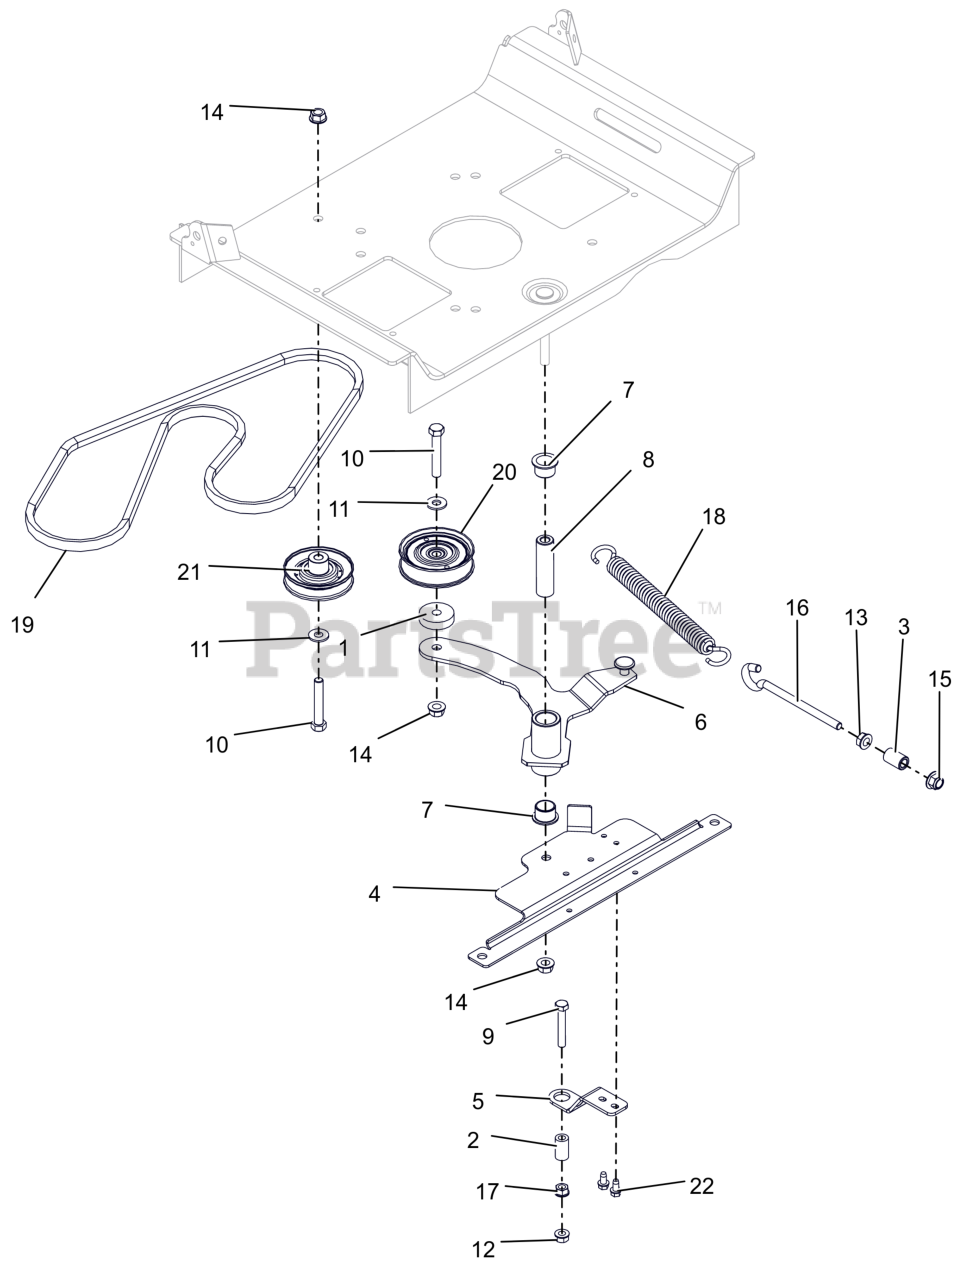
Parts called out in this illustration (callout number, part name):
1	SPACER, .39 X 1.50 X .380
2	SPACER, RUBBER 5/16 IDX1.0 LG
3	SPACER, .375X.625X.970 (PM)
4	BRKT, IDLER ATTACHMENT
5	BRKT, CLUTCH STOP (XL)
6	WLDMT,GRD DRIVE IDLER ARM-LGR
7	BSHG-FLG 0.75X0.875X.625X1.125
8	BUSHING, SLEEVE .38X.750X2.78
9	BLT, HEX .31-18X2.00 G5 ZCC
10	BLT,HEX .38-16X2.25 G5 ZCC
11	WSHR,FLT .375X.875X.083 ZCC
12	NUT-LK-TOP-FLG .312-18 GF ZCC
13	NUT, SPNLK-FLG .38-16 G5 ZCC
14	NUT-LK-TOP-FLG .38-16 ZC120
15	NUT,NYL-FLG .38-16 GF ZCC
16	BOLT,.38-16 X 4.25-.62 DIA EYE
17	NUT,SPNLK-FLG .31-18 G5 ZCC
18	SPRING, EXTENSION
19	V-BELT, A-RAW EDGE
20	IDLER, FLAT - 3.05" X .75"
21	IDLER, V-3.000 OD
22	SCR-TAP .25-20X.50 HWH ZCC
